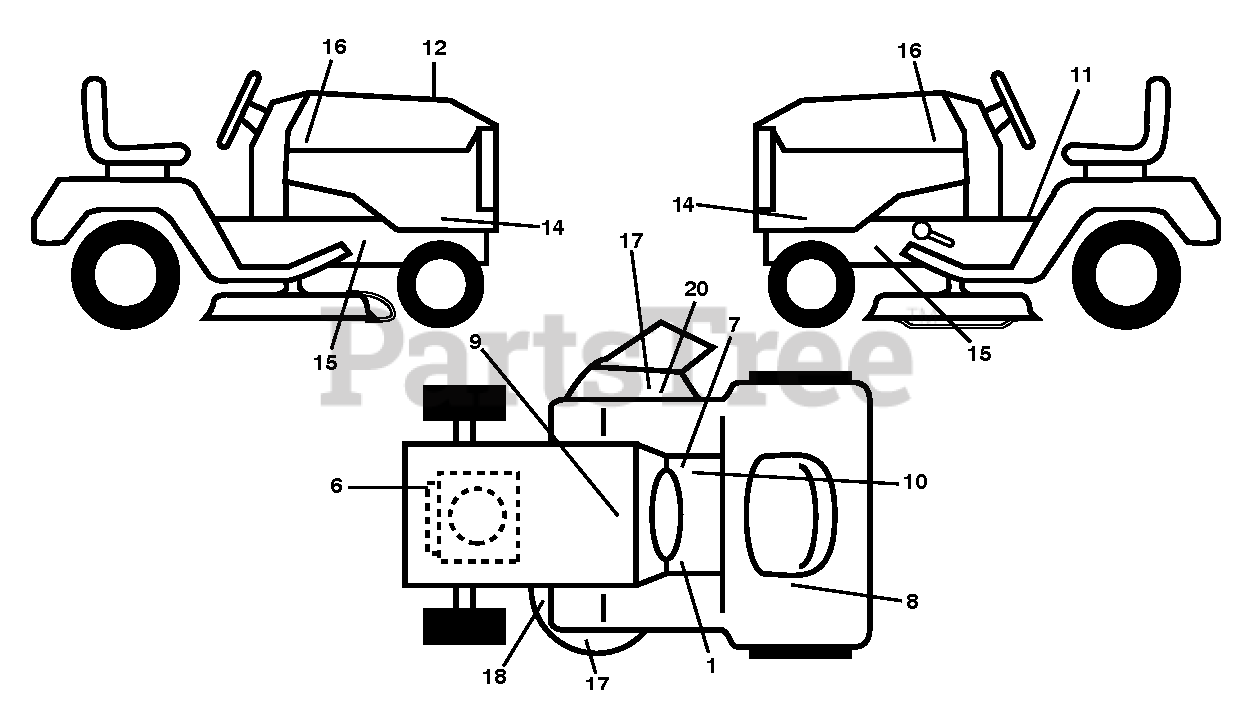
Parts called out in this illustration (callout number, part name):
1	DECAL.FNDR.SDLE.BRAKE.CLUTCH.6
6	DECAL.ENGINE.WARNING
7	DECAL.PARKING.BRAKE.SADDLE.LT
8	DECAL.RESERVEFUELSELCTR.ENG
9	DECAL BTRY SYMBOLS
10	DECAL.FWD/REV.PEDAL.SYMBOL
11	DECAL.READ.OWN.MAN.SYMBOL.LT
12	DECAL.RPL.BSM38.VAN.TLB.48F
14	DECAL.SDPNL.HUSQGT.TS348.RH/LH
15	DECAL.CHASSIS.HOT.MUFFLER
16	DECAL.BADGE.170MM.TEXTLOGO.
17	DECAL.DECK.6MIL.EURO.NOSTEP
18	DECAL.MOWER.SCH.48/54.PREM
20	DECAL, DECK DEFLECTOR, WARNING
